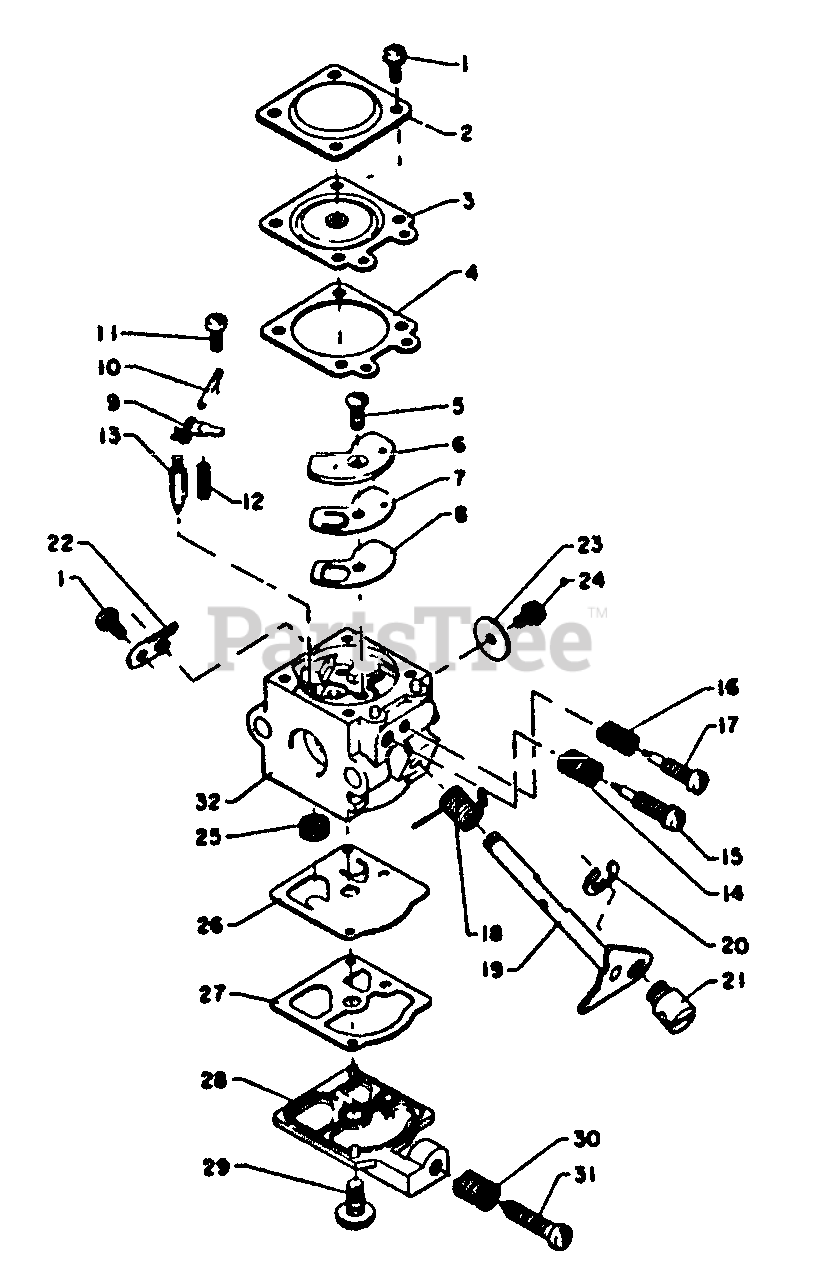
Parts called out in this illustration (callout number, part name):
2	COVER, METERING DIAPHRAGM
3	DIAPHRAGM, METERING
4	GASKET, METERING DIAPHRAGM
5	SCREW, CIRCUIT PLATE
6	PLATE, CIRCUIT
7	VALVE, CHECK
8	GASKET, CIRCUIT PLATE
9	LEVER, METERING
10	PIN, METERING LEVER
11	SCREW, METERING LEVER PIN
13	VALVE, INLET NEEDLE
14	SPRING, NEEDLE
15	NEEDLE, HIGH SPEED
16	SPRING, NEEDLE
17	NEEDLE, IDLE
18	SPRING, THROTTLE RETURN
19	SHAFT, THROTTLE
20	RING, RETAINING
22	CLIP, THROTTLE SHAFT
23	VALVE, THROTTLE
25	STRAINER
26	DIAPHRAGM, FUEL PUMP
27	GASKET, FUEL PUMP
28	COVER, PUMP
30	SPRING, IDLE ADJUST
31	SCREW, IDLE ADJUST
32	BODY, CARBURETOR
